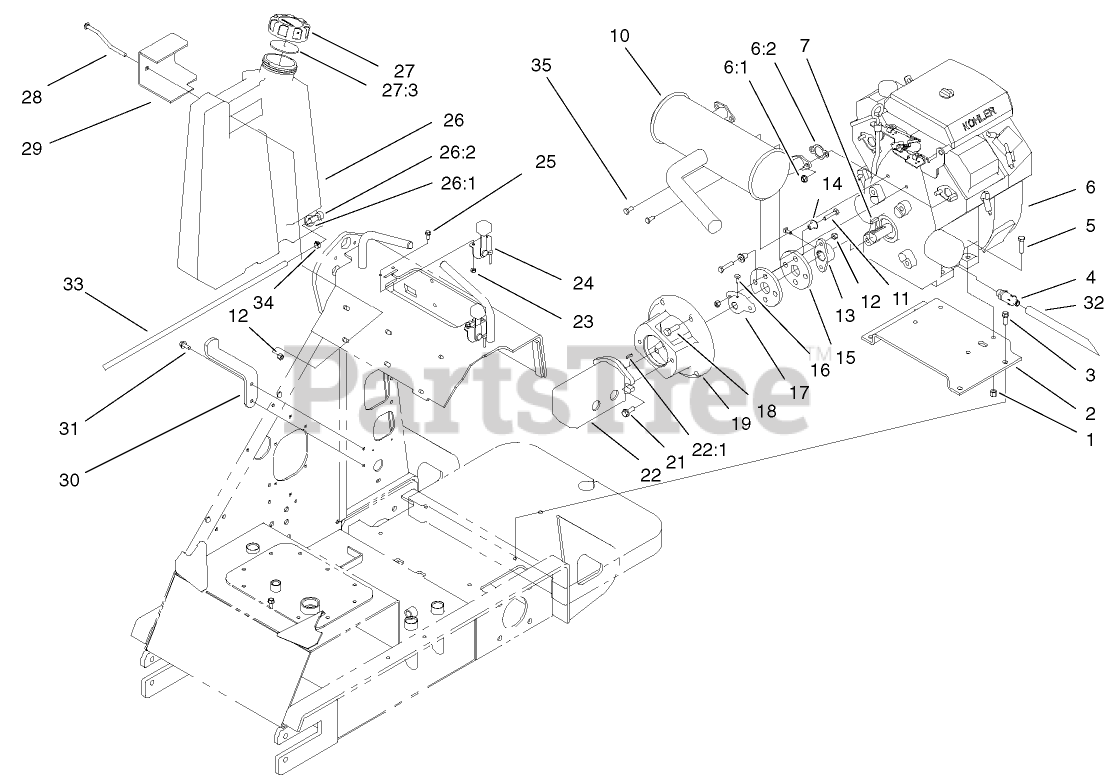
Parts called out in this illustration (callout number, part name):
1	NUT-LOCK, NI
2	MOUNT-ENGINE
3	SCREW-TAPTITE
4	VALVE-DRAIN, OIL
5	SCREW-HH
6:1	NUT-HF
6:2	GASKET-EXHAUST
7	KEY-SQUARE
10	MUFFLER-KOHLER
11	SCREW-HH
12	NUT-LOCK, NI
13	HUB-ENGINE
14	SPACER
15	COUPLING-RUBBER
16	SCREW-SQH
17	HUB-PUMP
18	SCREW-HH
19	MOUNT-PUMP
21	SCREW-HHF
22	PUMP-GEAR, TANDEM
22:1	KEY-SQUARE
23	NUT-LOCK, NI
24	CONTROL-CHOKE / THROTTLE
25	SCREW-HHF
26	RH FUEL TANK ASM
26:1	BUSHING
26:2	VALVE-FUEL
27	CAP-FUEL, GAS
27:3	GASKET-VENTED
28	BOLT-MOUNT
29	PLATE-MOUNT
30	MOUNT-BOTTOM, TANK
31	SCREW-HWHTF
33	HOSE-FUEL
34	CLAMP-HOSE
35	SCREW-HH
